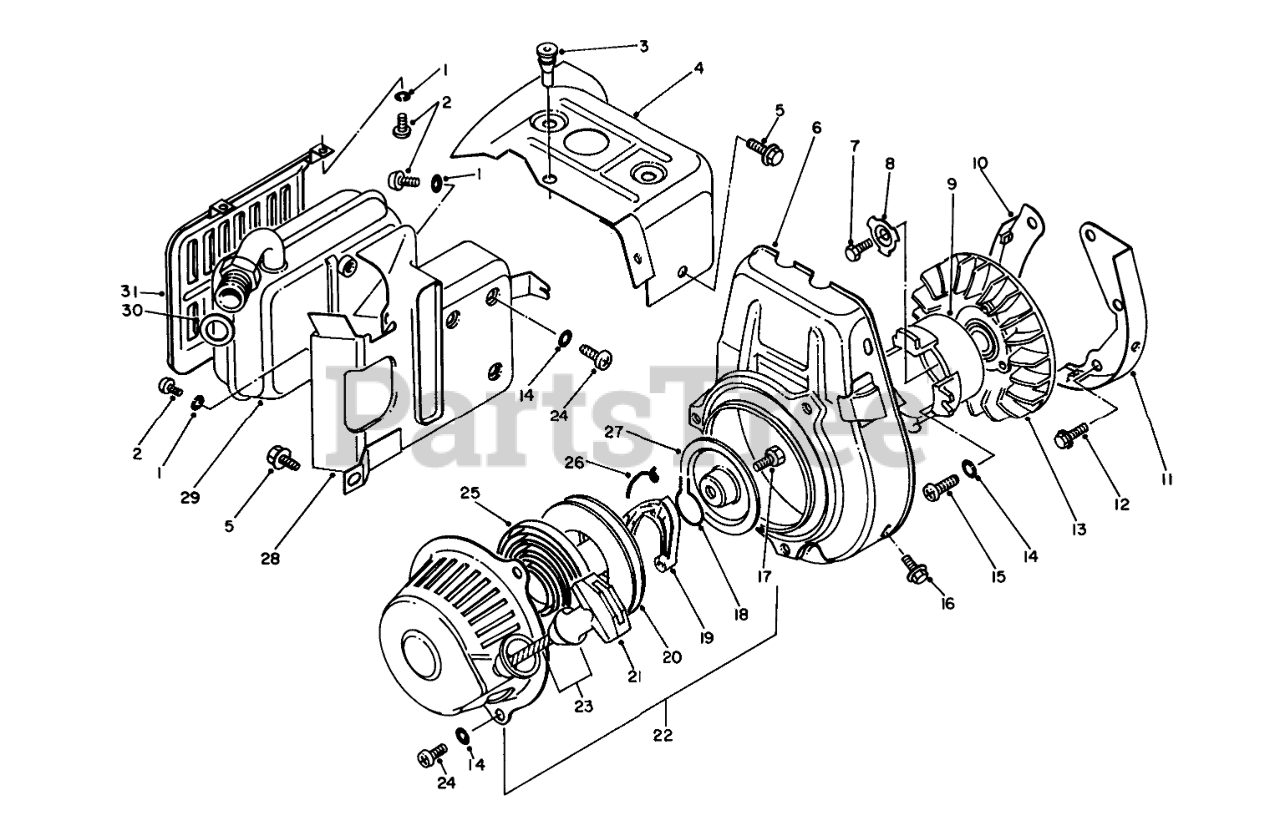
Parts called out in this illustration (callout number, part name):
1	Washer
2	Screw
3	Cushion
4	Cowling-Ventilation
6	Cover-Cooling Fan
8	Washer
9	STARTER ASM
10	Plate-Cooling Fan Rear
11	Plate-Cooling Fan Front
13	Fan-Cooling
14	Lockwasher
15	Screw
18	Spring
19	Ratchet
21	Grip
22	Starter Assembly-Recoil
23	Grip Assy. (Incl. Ref. #21)
24	Screw
25	Spring
26	Spring-Return
27	Plate-Friction
28	Cover-Rear
29	Muffler
30	Gasket-Exhaust
31	Cover-Front
